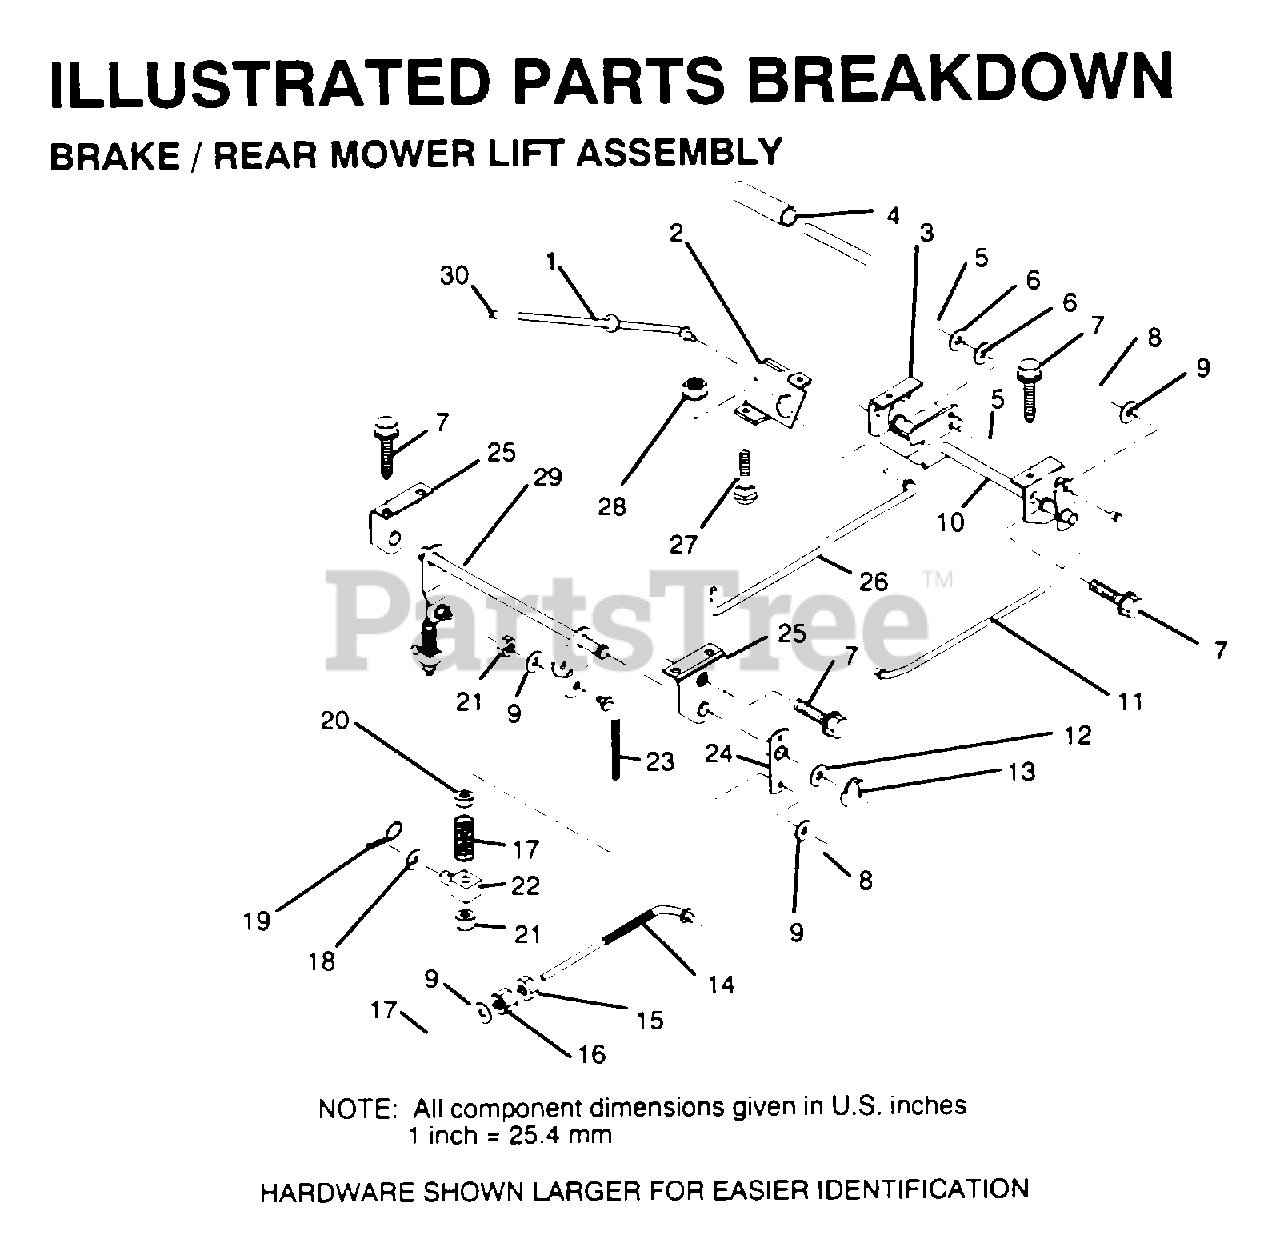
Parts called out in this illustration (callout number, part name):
1	"ROD,PARK BRAKE"
2	"BRKT,PARK BRAKE"
3	"BRKT,CLU PEDAL LH"
4	PEDAL COVER T
6	WASHER
7	SCREW LT
8	COTTER PIN
9	WASHER
11	"ROD,FRT BRAKE"
12	WASHER T
13	KLIP RING
15	NUT
16	NUT
17	SPRING ROD LT
18	WASHER
19	SPRING.RETAINER
20	LOCKNUT
23	"LINK.LIFT.3.5"""
24	BRAKE PIVOT ARM
25	"BRKT,LIFT SHAFT"
26	"ROD,CLUTCH"
29	REAR MOWER LIFT
30	PLUNGER CAP T
